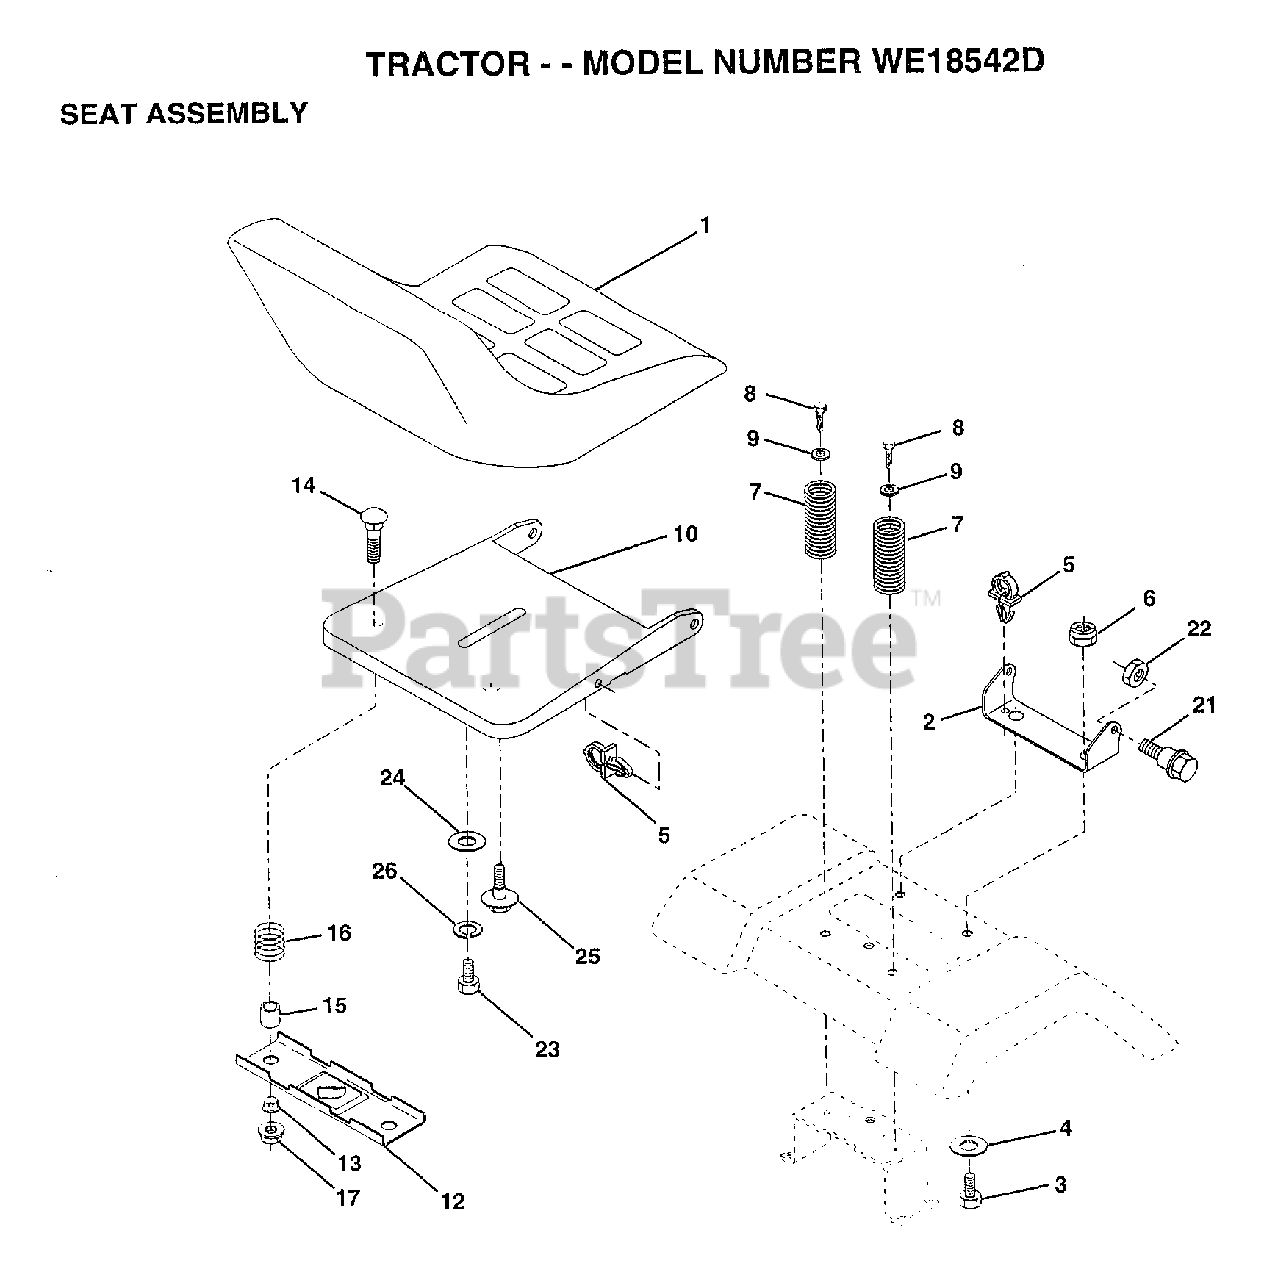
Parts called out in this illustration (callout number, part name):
2	BRACKET PVT SEAT
3	BOLT
4	WASHER PM
5	CLIP.PUSH-IN.HING
6	NUT
7	SPRING COMPRESSIO
8	SCREW GTV
9	WASHER
10	PAN-SEAT
12	BRKT SWITCH
13	BUSHING
14	BOLT-RD HD SQ NK
15	SPLIT SPACER
16	SPRING
21	"BOLT,SHOULDER"
22	NUT
23	BOLT
24	WASHER
25	"BOLT,SHOULDER"
26	LOCKWASHER
